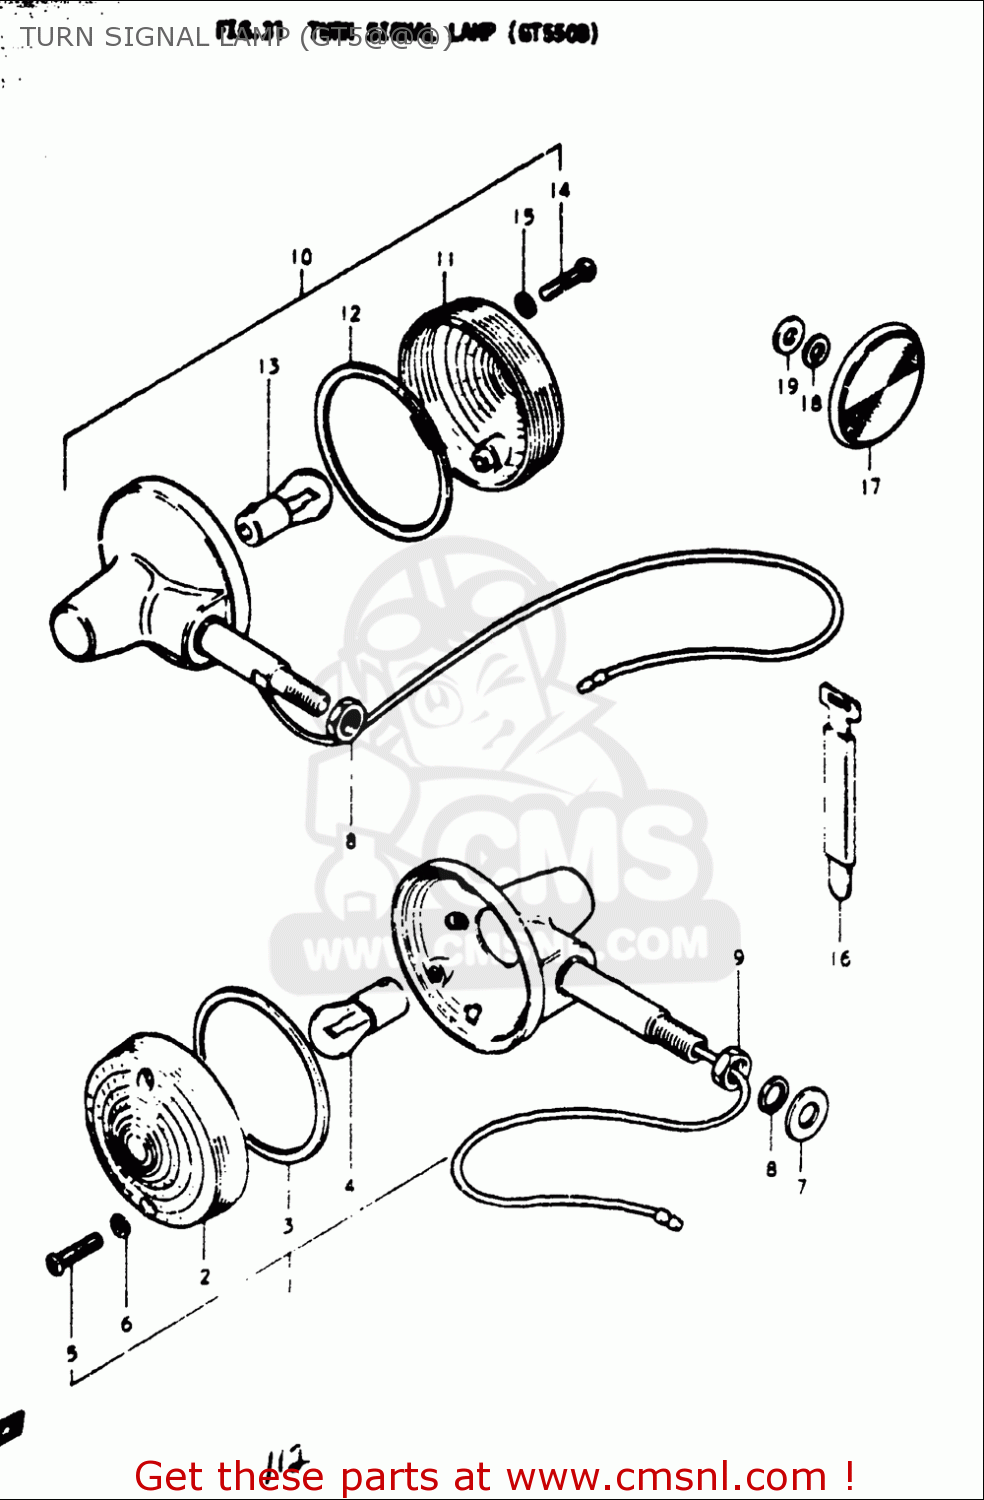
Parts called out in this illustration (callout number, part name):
1	LAMP ASSY,FR TURN SIGNAL
2	LENS
3	GASKET (NAS)
4	BULB(12V23W,STANLEY,A4577A)
6	GASKET (NAS)
7	WASHER
8	WASHER,LOCK
9	NUT
10	LAMP ASSY,RR TURNSIGNAL
11	LENS
12	GASKET (NAS)
13	BULB(12V23W,STANLEY,A4577A)
15	GASKET (NAS)
16	CLAMP
17	REFLEX REFLECTOR,FR
18	WASHER,LOCK
19	WASHER
